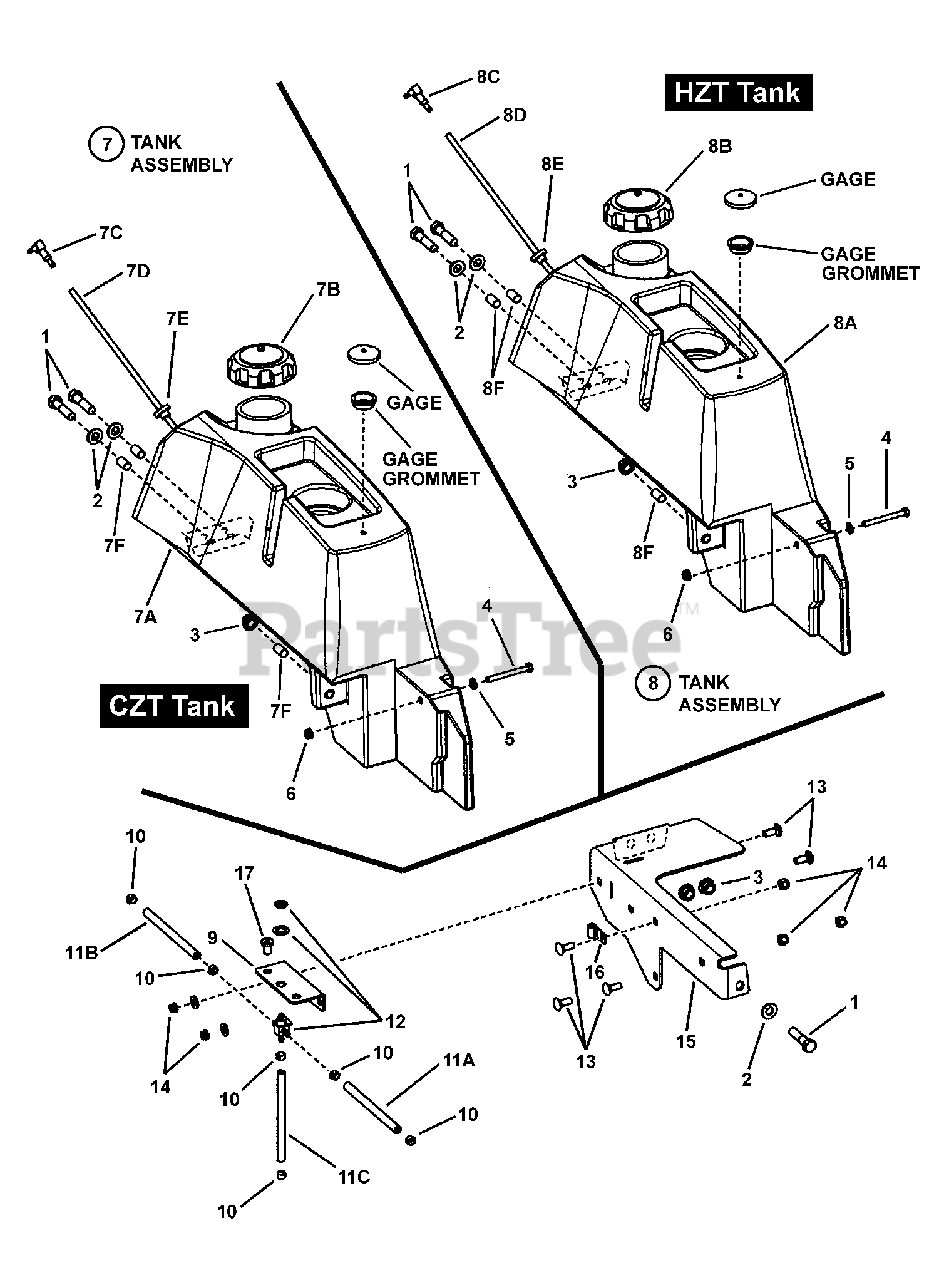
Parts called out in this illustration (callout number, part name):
1	SCREW, 7/16-14 x 2" Hex Head Cap, GR 5
2	WASHER, 1/2" Flat SAE
3	NUT, 7/16-14 HEX NYLON LOCK
4	BOLT, 5/16-18 X 2-1/2" GD5 YZ
5	WASHER, 5/16" Flat
6	NUT, 5/16-18 HEX NYLON LOCK
7	ASSEMBLY, L.H. Tank CZT (incl. 6 items shown below)
7A	FUEL TANK, LH
7B	CAP, Fuel, 3-1/2"
7C	ELBOW, 90-degree
7D	DIP TUBE, .261 I.D. x 24-1/4"
7E	GROMMET, Dip Tube
7F	SPACER
8	ASSEMBLY, L. H. Tank HZT (incl. 6 items shown below)
8A	FUEL TANK, LH
8B	CAP, Fuel, 3-1/2"
8C	ELBOW, 90-degree
8D	DIP TUBE, .261 I.D. x 24-1/4"
8E	GROMMET, Dip Tube
8F	SPACER
9	BRACKET, Auxiliary Fuel Valve
10	CLAMP, Fuel Hose
11A	FUEL HOSE, 1/4" I. D. x 49" (RH)
11B	FUEL HOSE, 1/4" I.D. x 17" long
11C	FUEL HOSE, 1/4" I.D. x 1' Long
12	ASSEMBLY, 3-Way Fuel Valve
13	BOLT, 3/8-16 x 1" Square Neck Carriage, GR 5
14	NUT, 3/8-16 HEX NYLON LOCK
15	WELDMENT, L.H. Tank Bracket
16	CLIP, Harness
17	WELL-NUT, 1/4-20 x 53/64
